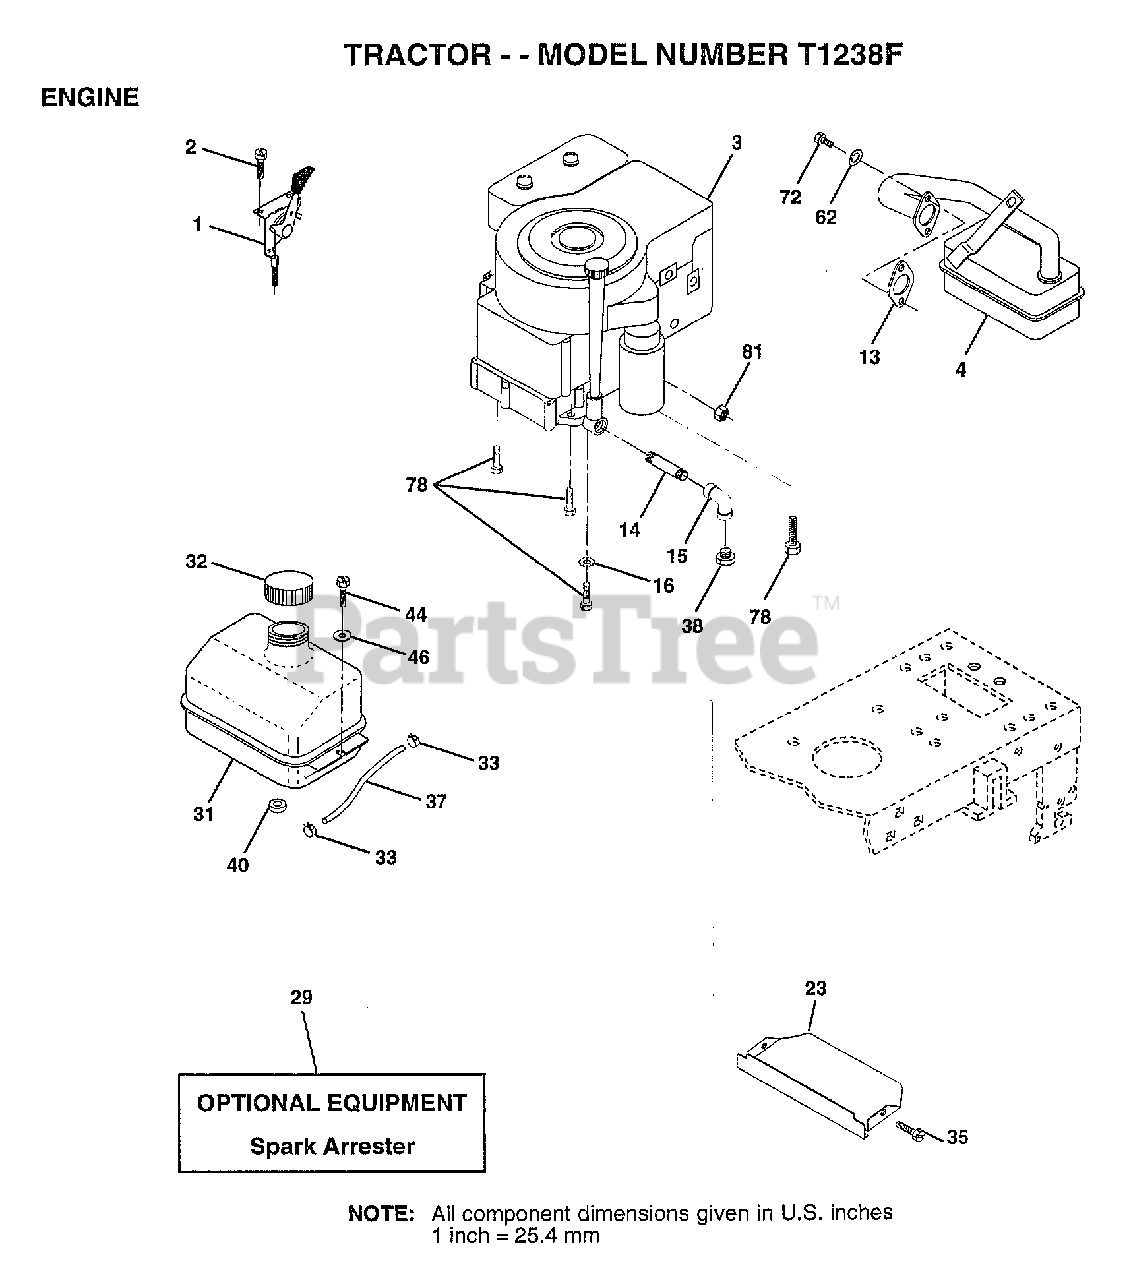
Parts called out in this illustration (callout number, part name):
1	THROTTLE CONTROL
2	SCREW LT
4	MUFFLER
13	GASKET ENG 1 313 LD TIN PLATED
14	PIPE NIPPLE
15	ELBOW
16	LOCKWASHER
23	SHIELD.BRN/DBR.GD
31	TANK.FUEL.LT.
32	CAP ASM FUEL
33	HOSE CLAMP
37	LINE FUEL
44	SCREW HEX CRT
46	WASHER
62	LOCKWASHER
72	SCREW
78	SCREW
81	NUT
